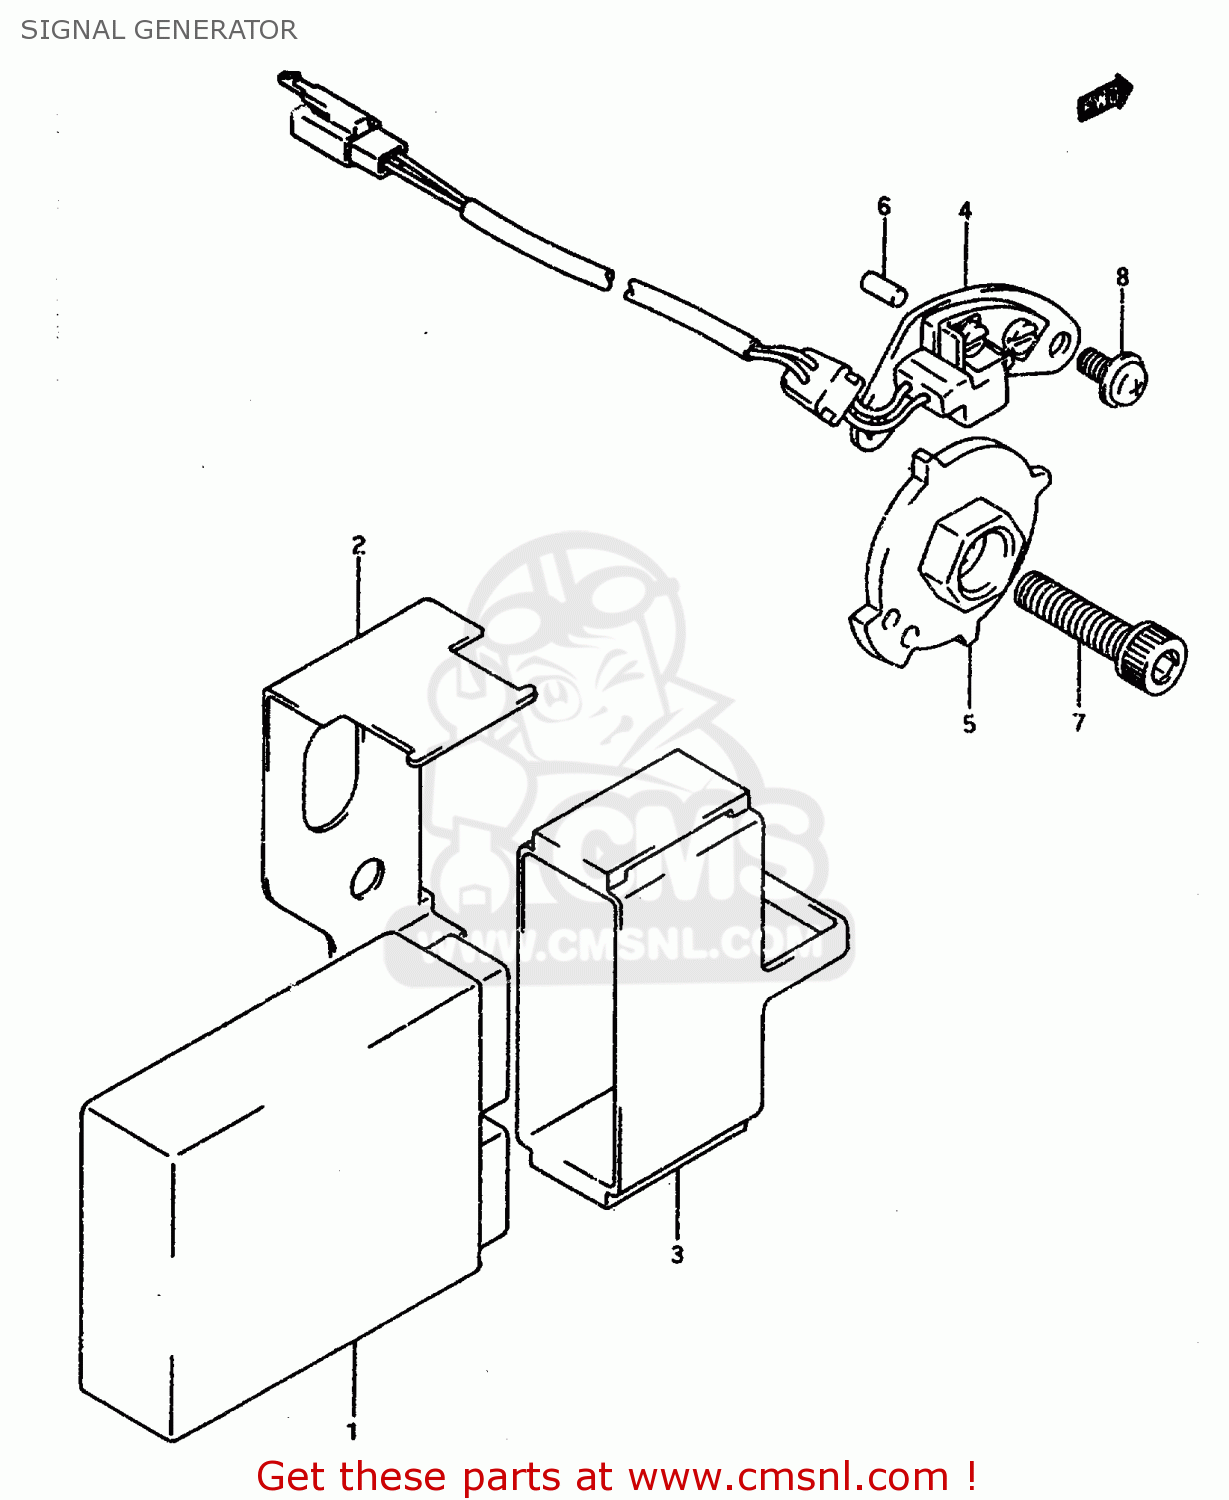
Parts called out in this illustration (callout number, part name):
1	IGNITER
2	BRACKET,IGNITOR
3	CUSHION,IGNITOR
4	STARTER,SIGNAL GENERATOR
5	ROTOR,SIGNAL GENERATOR
6	PIN
7	BOLT
8	SCREW
